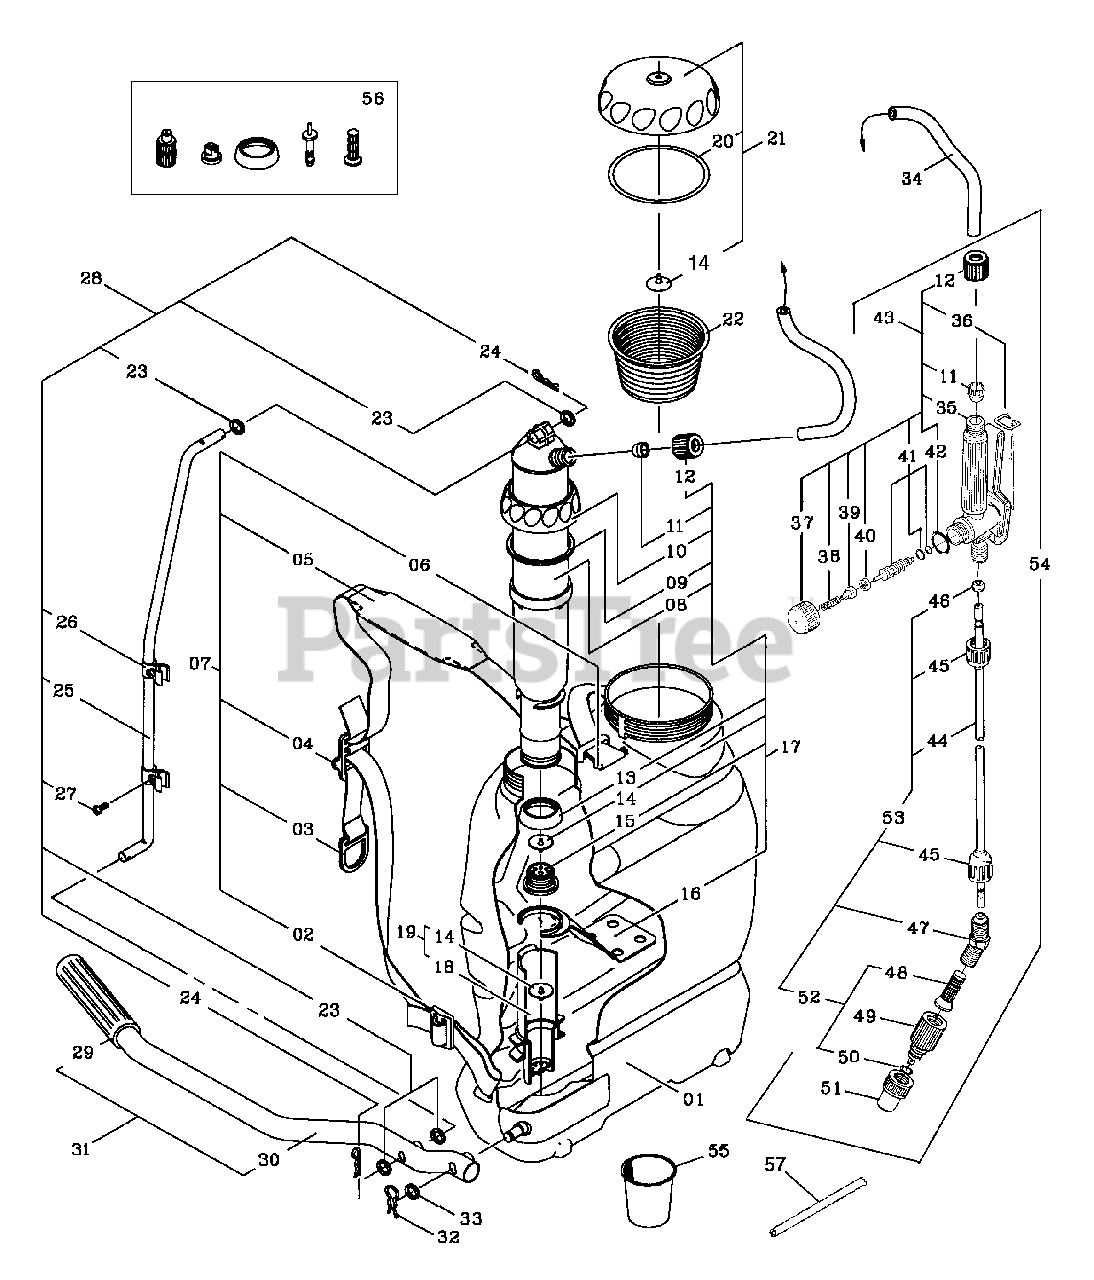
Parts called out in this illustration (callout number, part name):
1	TANK-SP300
2	SHOULDER STRAP BUCKLE - LOWER
3	LOWER STRAP ASSEMBLY
4	SHOULDER STRAP BUCKLE
5	SEAL - UPPER -- 50×96×35
6	SHOULDER STRAP RETAINING CLIP
7	SHOULDER STRAP ASSEMBLY
8	CHAMBER BODY
9	CHAMBER PACKING RING (VITON)
10	PACKING NUT RING
11	HOSE FERRULE
12	NUT, 20×1.5
13	PISTON CUP - 45×12
14	VALVE, DIAPHRAGM
15	PISTON CUP FASTENER
16	AGITATOR
17	CHAMBER ASSEMBLY
18	CYLINDER
19	CYLINDER ASSY
20	O-RING CAP SEAL ORI - 245
21	TANK CAP WITH SEAL AND DIAPHRAGM
22	STRAINER, DEBRIS
23	WASHER
24	RETAINING CLIP
25	PUMP LEVER CONNECTING ROD
26	SPRAY WAND HOLDING CLIP
27	SCREW - 3.5×16
28	PUMP LEVER CONNECTING ROD ASSEMBLY
30	PUMP LEVER
31	PUMP LEVER ASSEMBLY (29 & 30)
32	RETAINING CLIP
33	WASHER
34	HOSE
35	TRIGGER VALVE BODY W/HANDLE
36	TRIGGER VALVE LOCK
37	TRIGGER VALVE CAP
38	SPRING
39	VALVE SEAT BASE
40	SEAT, VALVE
41	TRIGGER NEEDLE VALVE ASSEMBLY
42	O-RING ORI - 019
43	TRIGGER VALVE ASSY
44	SPRAY WAND TUBE
45	SCREW - SOCKET HEAD CAP
46	CONE PACKING
47	SPRAY WAND NOZZLE ELBOW
48	FILTER, NOZZLE
49	NOZZLE BODY
51	NOZZLE CAP - RED
52	ADJUSTABLE CONE NOZZLE
53	SPRAY WAND TUBE ASSEMBLY WITH NOZZLE
54	SPRAY WAND ASSEMBLY COMPLETE
55	CALIBRATED MEASURING CUP
56	REPAIR KIT
57	DIAPHRAGM INSTALLATION TOOL
